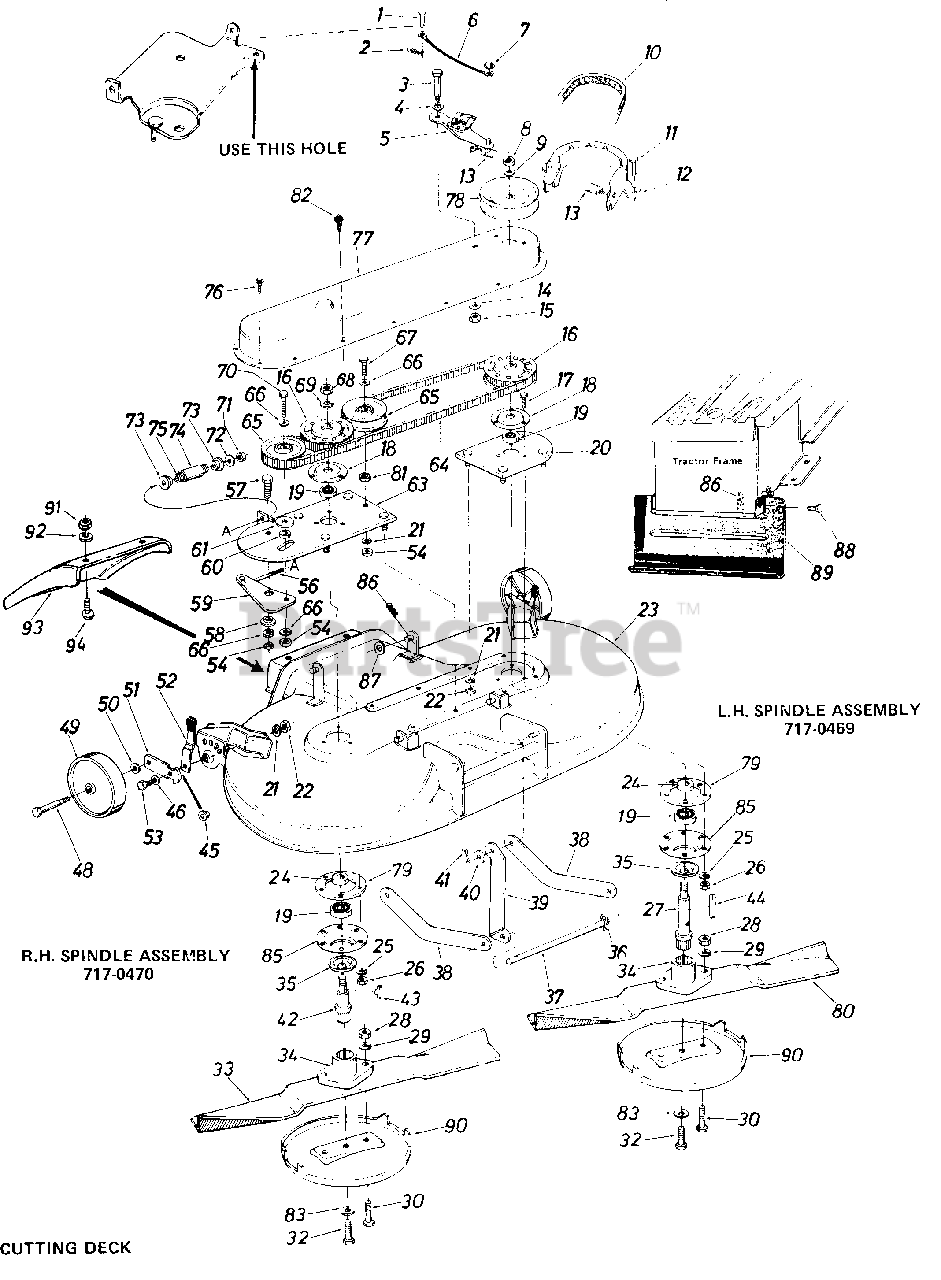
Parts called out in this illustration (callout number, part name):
1	Clevis Pin 1/4" Dia. x 1/2" Lg.
2	Hairpin Cotter 1/4" Dia.
3	Shld. Bolt .437" Dia. x.l0" Lg.
4	Wave Washer 7/16" Scr.
5	Spindle Brake Arm Ass'y.
6	Brake Cable Ass y.
7	Push Cap 1/4" Stud.
8	Hex Jam Nut 5/8-18 Thd.
9	Bell.-Wash. 5/8" I.D. x 1.25" O.D.
10	"V"-Belt 1/2" x 56" Lg.
11	HexWash. Hd.SelfTapScr. 1/4-20 x .50" Lg.
12	Belt Guard
13	Extension Spring
14	Bell.-Wash..340" I.D.
15	Hex Cent. L-Nut 5/16-18 Thd.
16	Sprocket Pulley Ass'y.
17	HexBolt5/16-24x 1.00" Lg. (Grade 5)
18	Bearing Housing
19	Ball Bearing.787" I.D. x 1.85" O.D.
20	Spindle Plate Ass'y.
21	L.-Wash. 3/8" I.D.
22	Hex Jam Nut 3/8-24 Thd.
23	44" R.D. Deck Ass'y.
24	Spacer
25	L.-Wash. 5/16" I.D.
26	Hex Nut 5/16-24Thd.
27	Blade Spindle-L.H.
28	Hex Nut 5/16-24 Thd.
29	L.-Wash. 5/16" I.D."
30	Hex Bolt 5/16-24 x 1.00" Lg.
32	Hex Bolt Cent. L.-3/8 x 24 x .38 " Lq.
33	22.5" Blade-L.H. Rotation
34	Blade Adapter
35	Bearing Shield
36	Hairpin Cotter
37	Deck Connecting Rod
41	Cotter Pin 3/32" Dia. x 1.00" Lg.
42	BladeSpindle-R.H.
43	Sq. Key 3/16" x 75" Lg.
44	Sq. Key 3/16" x 1.50" Lg.
45	Shoulder Spacer
46	Bell.-Wash..400" I.D.
48	Shld. Bolt 3/8-16 x 1.41" Lg.
49	Wheel Ass y. Comp. 6" x 1.38
50	Bell-Wash. 3/8" I.D.
51	Wheel Pivot Bar
52	Spring Lever Ass'y. w/knob
53	Hex Bolt 3/8-24 x 1.25" Lg. Grade 5
54	Hex Cent. L-Nut 3/8-24 Thd
56	Adjustment Link 5/16-18 x 4-9/16" Lg.
57	Hex Bolt 3/8-24 x 1.00"
58	Shld. Spacer .625" I.D.
59	Belt Idler Brkt.
60	Spacer.380" I.D. x .625" O.D. x.265
61	Fl.-Wash. .38" I.D. x 1.37" O.D. x .125
63	Spindle & Idler Mount Plate Ass'y.
64	HTD Twin Power Belt
65	Fl.-IdlerPulley 3.50" O.D.
66	Bell.-Wash..38" I.D.
67	Hex Bolt 3/8-24 x 1.75" Lg. (Grade 5)
68	Hex Jam Nut 5/8-18 Thd.
69	Bell.-Wash. 5/8" I.D.
70	Hex Bolt 3/8-24 x 2.00" Lg.
71	Hex Insert L.-Nut 5/16-18 Thd.
72	Fl.-Wash. 344" I.D. x 1.125" O.D. x .125
73	Shld. Spacer.625" I.D.
74	Spacer-Adj. Bolt
75	Compression Spring
76	Hex \IVash. Hd. Self Tap. Scr. 1/4-20 x . 50" Lg.
77	Belt Cover
78	Deck Drive Pulley
79	Deck Reinforcement Plate
80	22.5" Blade-R.H. Rotation
81	Fl.-Wash. .38" I.D. x 1.00" 0. D.
82	Hex Wash. Hd. Self Tap-Scr. 1/4-20x.75" Lg.
83	L.-Wash. 3/8" I.D. Heavy Duty
86	Hairpin Cotter
87	Fl.-Wash. 1/2" I.D.
88	Clevis Pin
89	Safety Shield-16 5/8" Lg.
90	Anti Scalp Plate
91	Hex Nut 1/4-20 Thd.
92	L.-Wash. 1/4" I.D.
93	Chute Deflector
94	Truss Mach. Scr. 1/4-20 x.50" Lg.
